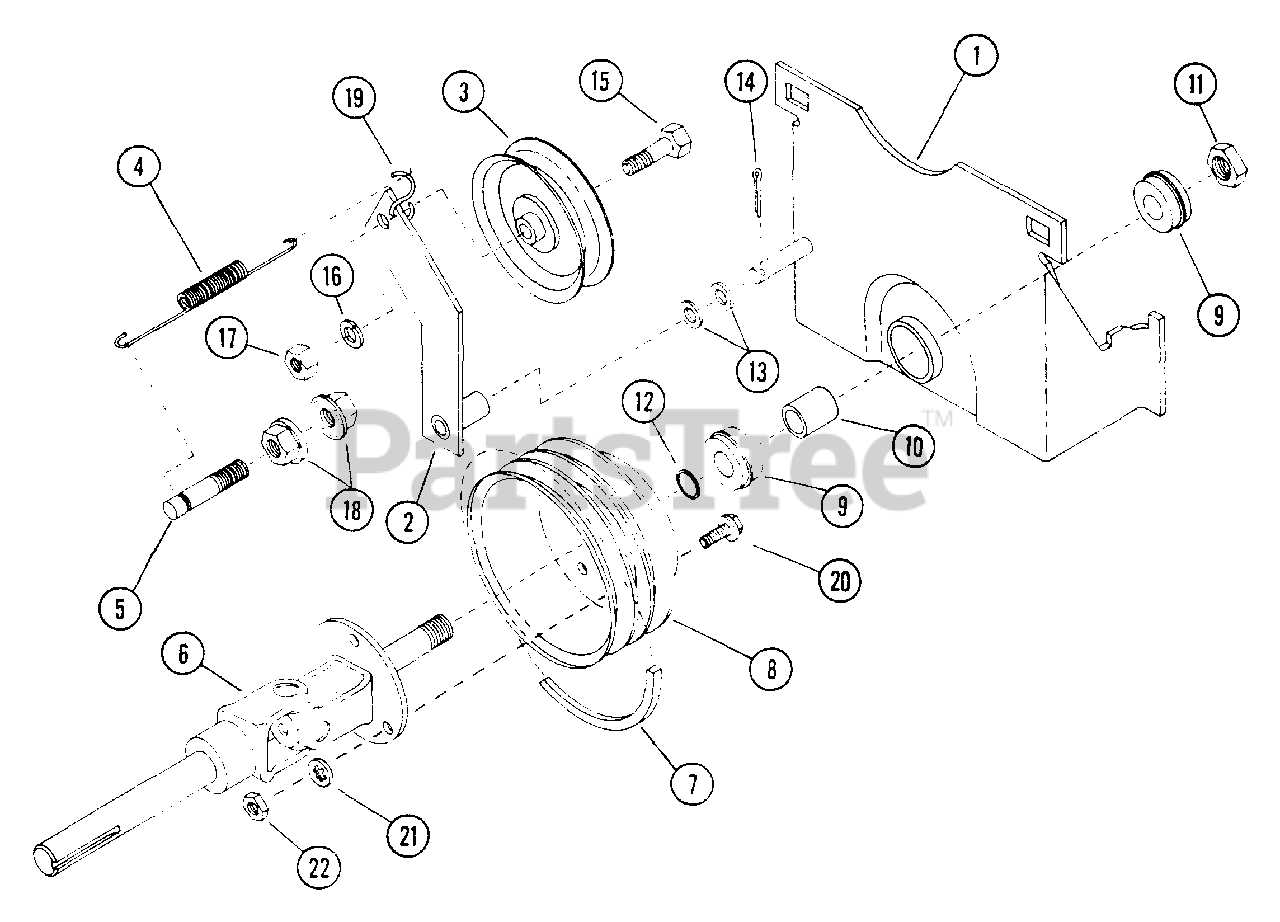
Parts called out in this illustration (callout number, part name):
1	BRACKET, Drive Mounting
2	ARM, Idler
3	IDLER, Flat (4.12 O.D.)
4	SPRING, Idler to anchor
5	ANCHOR, Spring (1/2-13 thread)
6	DRIVE-SHAFT, (Universal)
7	BELT, Drive
8	PULLEY, Offset
9	BEARING
11	LOCKNUT, 5/8-18 Hex Jam
12	WASHER, Shim
13	WASHER, 3/8 SAE (Flat)
14	COTTER-PIN, 3/32x3/4
15	CAPSCREW, 3/8-Cx1-1/2 Hex Head
16	LOCKWASHER, 3/8 Split
17	NUT, 3/8C Hex
18	LOCKNUT, 1/2-13 Hex Flange
19	S-HOOK
20	CAPSCREW, 1/4Cx3/4 Hex
21	LOCKWASHER, 1/4 Internal Tooth
22	NUT, 1/4C Hex
